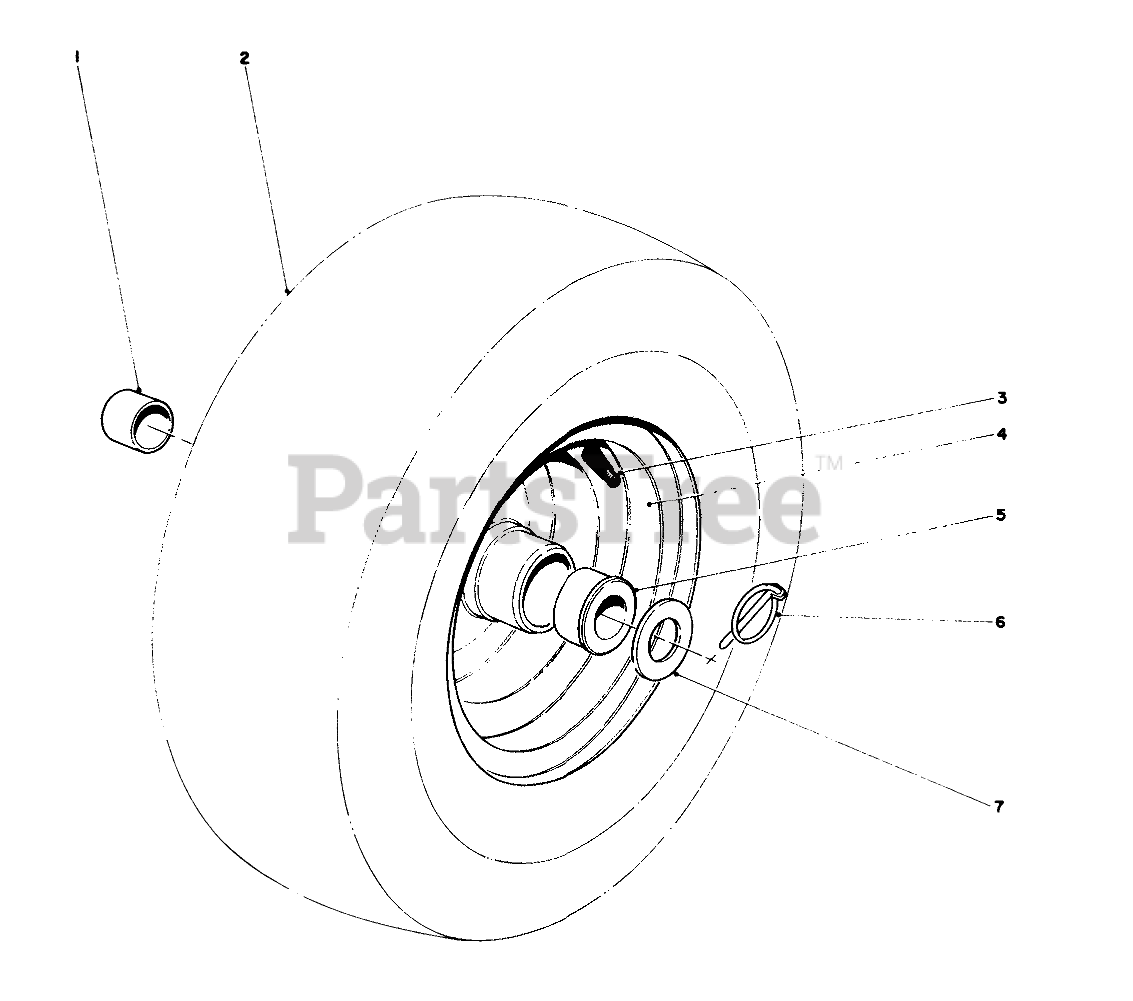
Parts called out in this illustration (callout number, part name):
1	.877ID X .750LG BSHG
2	Tire
3	STEM-VALVE
4	Wheel & Hub Assembly (Incl. Ref. # 1 & 5)
5	BUSHING
6	PIN-LYNCH
7	WASHER-THRUST
